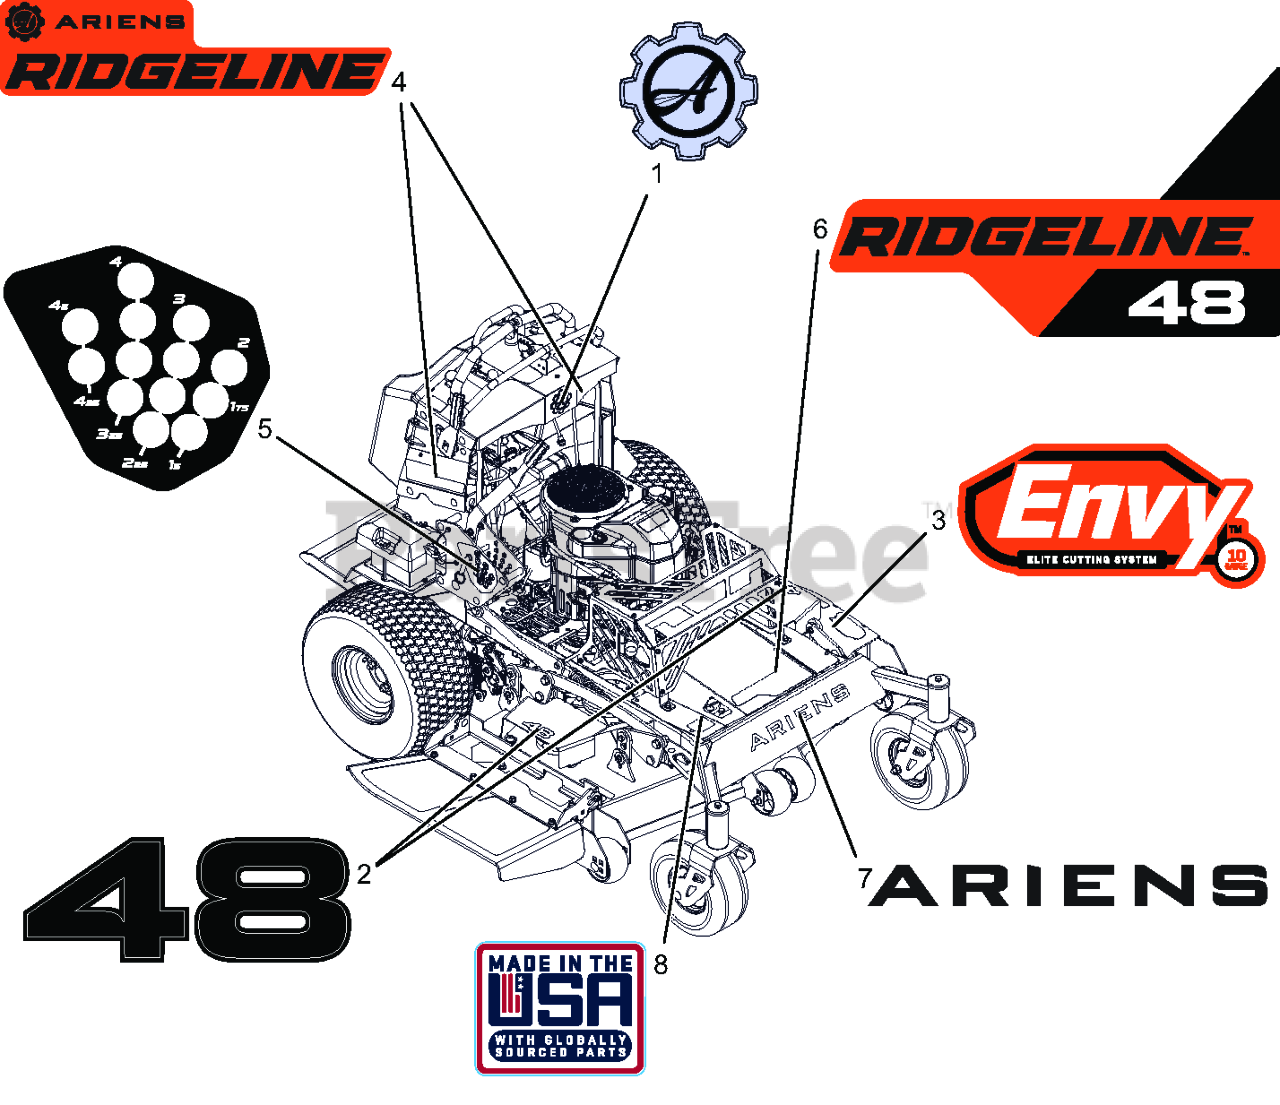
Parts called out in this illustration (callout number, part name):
1	DECAL- ARIENS GEAR BADGE
2	DECAL- DECK 48
3	DECAL- DECK -ENVY
4	DECAL- TOWER
5	DECAL- HOC
6	DECAL- RIDGELINE 48"
7	DECAL- ARIENS 15.0" BLACK
8	DECAL, MADE IN USA
